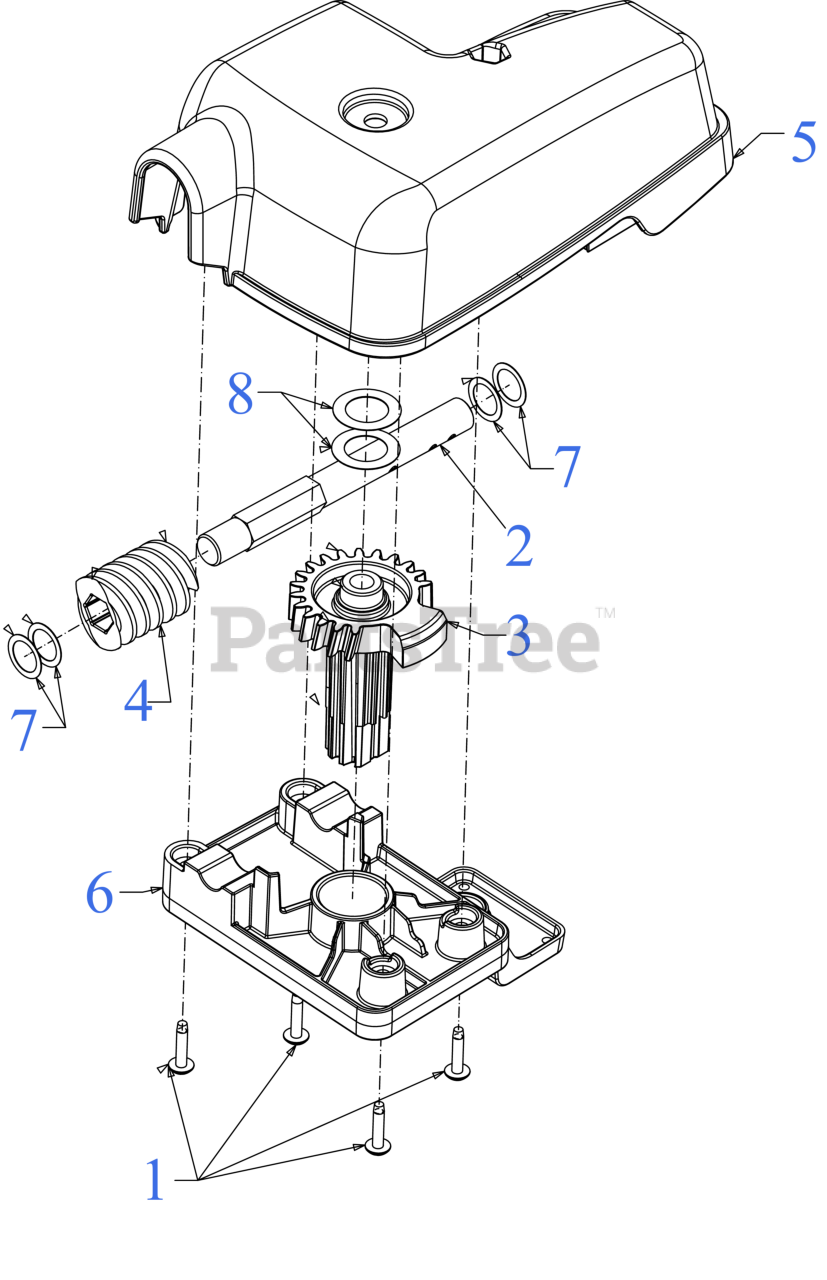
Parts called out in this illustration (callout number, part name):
1	SCREW 8-16 x 3/4
2	HEX SHAFT
3	HELICAL GEAR- 23
4	NYLON WORM
5	CHUTE CONTROL GEAR COVER (2WAY)
6	CHUTE HOUSING GEAR BASE
7	FLAT WASHER .504 X.700X.010
8	SHIM WASHER .632X1.000X.010:HD
